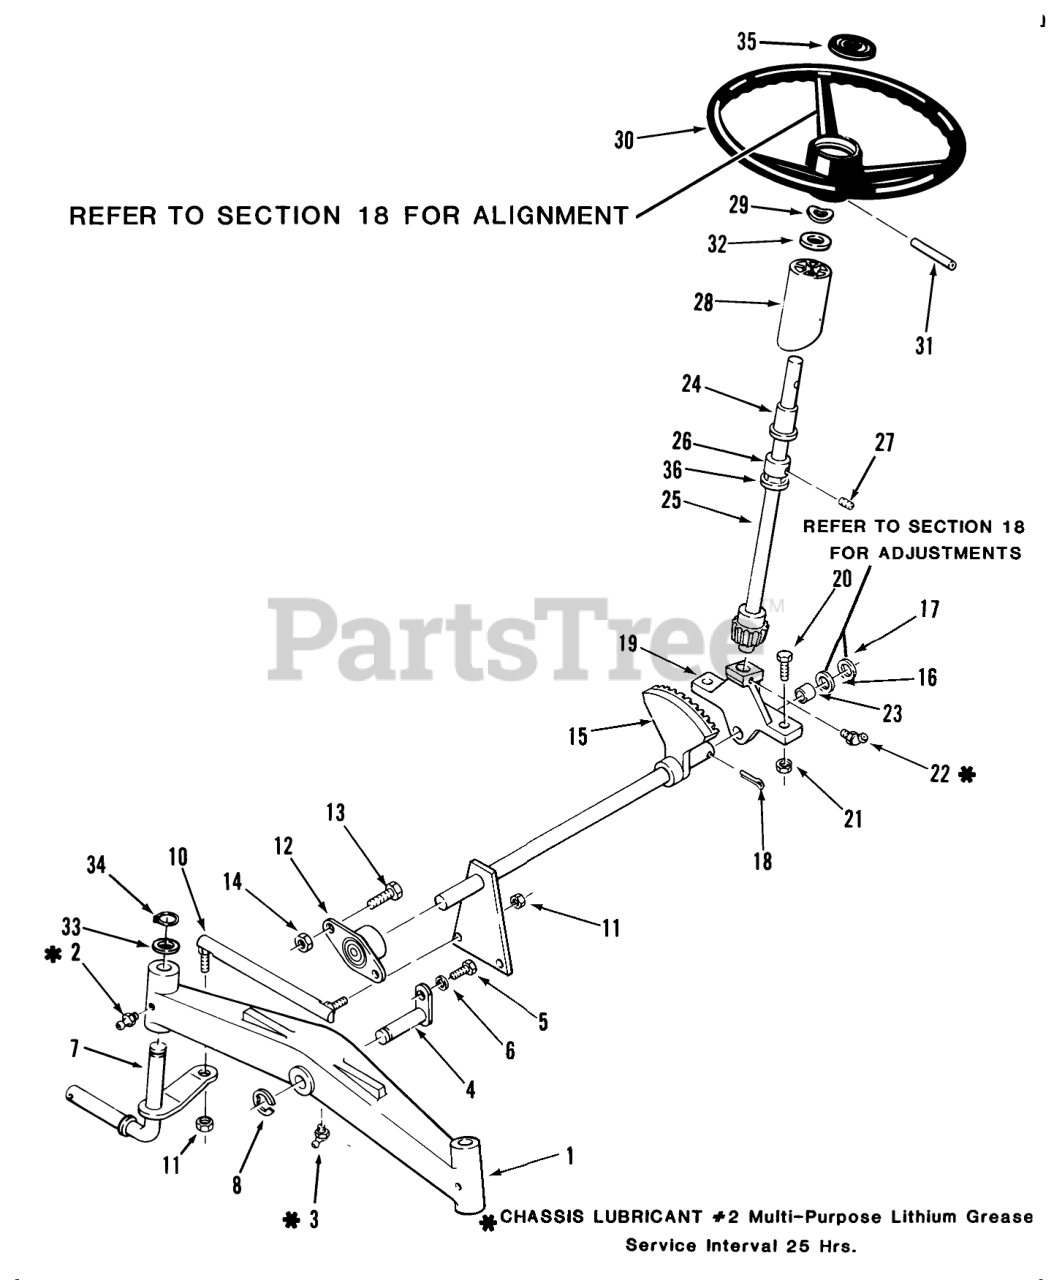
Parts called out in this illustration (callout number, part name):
1	AXLE-FRONT
2	Zerk
3	FITTING-GREASE
4	PIN AND PLATE ASM
5	H H C S
6	Lockwasher
7	RH SPINDLE WA
7	LH SPINDLE ASM
8	E-RING
10	Tie Rod RH
11	NUT-6
12	BEARING-FLANGED
13	Bolt
14	Nut
15	ASS'Y-STRG SHAFT R
16	WASHER-SHIM
17	WASHER
18	PIN-4
19	Support
20	BOLT
21	Nut
22	FITTING-GREASE
23	BEARING-BRONZE
24	BEARING-FLANGED
25	Shaft-Upper Steering
26	Collar
27	SCREW-SET
28	TUBE-STEERING
29	WASHER-BOWED
30	STEERING WH 13" PLAS
31	Pin-Roll
32	WASHER-FLAT
33	WASHER
34	Snap Ring
35	STEERING WHEEL INSE
36	RING-RETAINING
